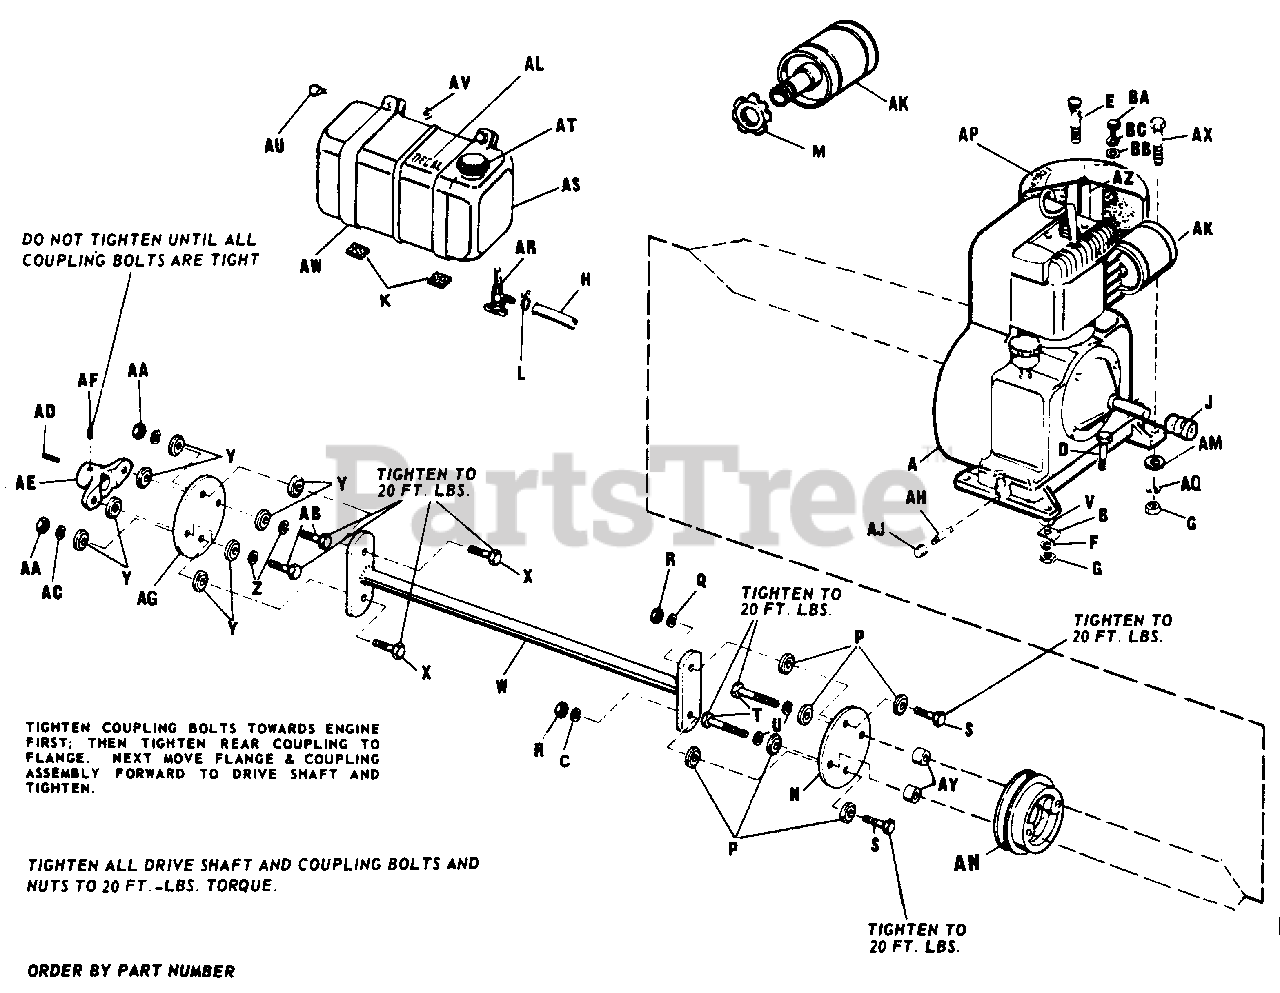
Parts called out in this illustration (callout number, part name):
A	ENGINE, Briggs & Stratton
B	Stop Axle
C	Lock Washer, 3/8"
D	Hex. Cap Screw, 3/8"-16 x 1 3/4"
E	Rect. Hd. Screw
F	Lock Washer, 3/8"
G	Full Hex. Nut, 3/8"-16
H	Fuel Hose (Flexible)
J	Crankshaft Extension Guard
L	Hose Clamp (For Service Only)
P	Special Washer
Q	Lock Washer, 3/8"
R	Full Hex. Nut, 3/8"-16
S	Hex. Cap Screw, 3/8"-16 x 1 1/4" Lg.
T	Hex. Cap Screw, 3/8"-16 x 2 1/2" Lg.
U	Lock Washer, 3/8"
V	Plain Washer, 3/8"
W	Drive Shaft Assembly
X	Hex. Cap Screw, 3/8"-16 x 1 1/4"
Y	Special Washer
Z	Lock Washer, 3/8"
AA	Full Hex. Nut, 3/8"-16
AB	Hex. Cap Screw, 3/8"-16 x 1 1/4"
AC	Lock Washer, 3/8"
AE	Drive Shaft Flange
AF	Cup Point Socket Head Set Screw, 3/8"-24 x 3/8"
AH	Pipe Nipple, 3/8" x 1" Lg.
AJ	Pipe Cap, 3/8"
AK	Exhaust Muffler
AL	Decal, Fuel Tank
AM	Plain Washer, 3/8"
AP	Film, Air Cleaner
AQ	Lock Washer, 3/8"
AR	Shut-Off Valve
AS	Fuel Tank
AT	Fuel Tank Cap
AU	Hex. Hd. Cap Screw, 1/4"-20 x 1 3/4"
AV	Full Hex. Nut, 1/4"-20
AW	Tank Strap
AX	Hex. Hd. Capscrew, 3/8"-16 x 2" Lg.
AZ	Air Cleaner Spacer
BA	Hex. Hd. Cap Screw, 1/4"-20 x 5/8"
BB	Plain Washer, 1/4"
BC	Lock Washer, 1/4"
